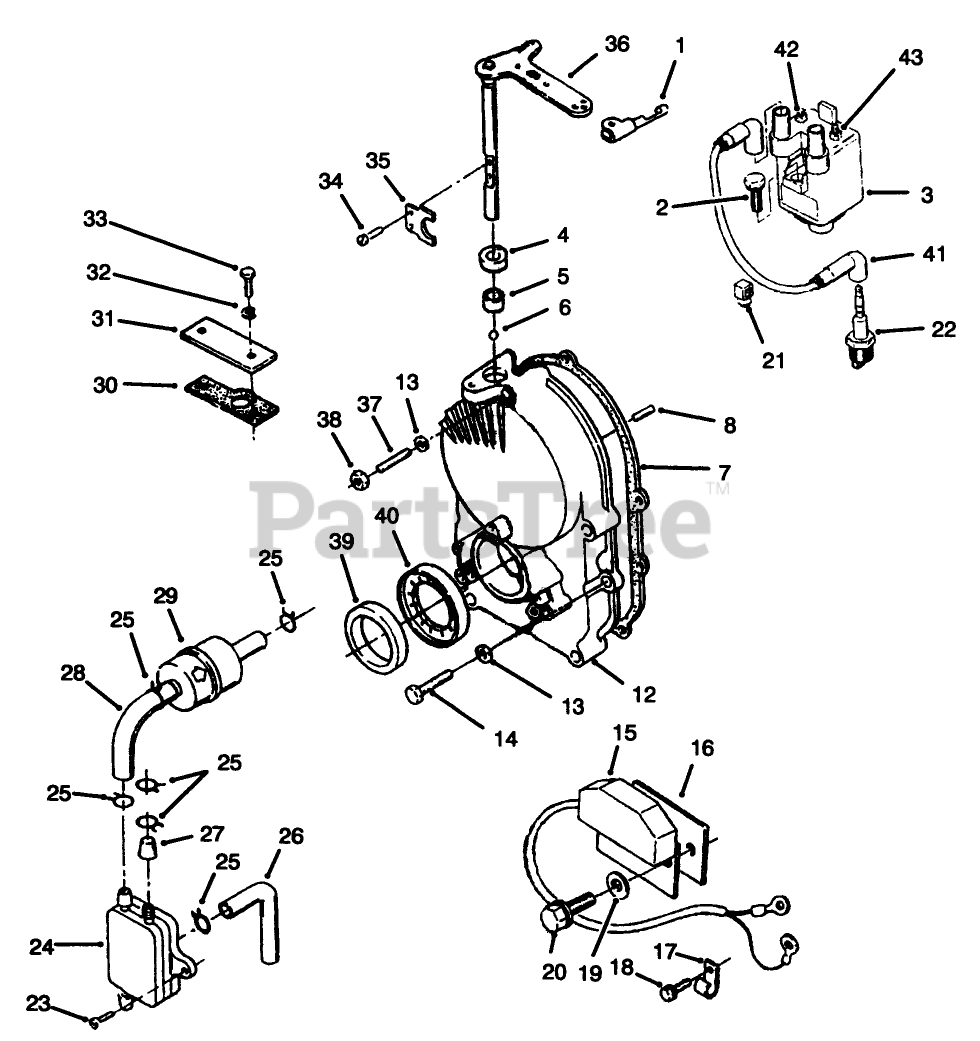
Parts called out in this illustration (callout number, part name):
2	SCREW-HH
3	COIL-BATTERY IGNITION
5	BEARING
7	GEAR CASE MTG GASKET
8	PIN-DOWEL
12	Kit-Gearcase (Incl. Ref. #4-6, 8-11, 26, & 34-36)
13	WASHER
14	SCREW-HH
15	CONTROL-IGNITION
16	INSULATOR-IGN MODULE
17	CLIP-WIRE
18	SCREW-HH
19	WASHER-LOCK, INT
20	SCREW-HH
21	WIRE ROUTING CLIP
22	SPARK PLUG
23	SCREW-TAPPING PAN HD
24	PUMP-FUEL
25	CLAMP
26	HOSE-VACUUM
27	CAP-FUEL OUTLET
28	Hose
29	FILTER-FUEL
30	GASKET
31	PLATE-COVER
32	WASHER-FLAT
33	SCREW-HH
34	Screw
36	SHAFT/ARM-GOVERNOR
37	STUD-GEAR COVER
38	NUT-HEX
40	ROTOR-IGNITION
41	Cable Plug 9" Long
42	NUT-HEX FLANGE
43	NUT-HEX FLANGE
